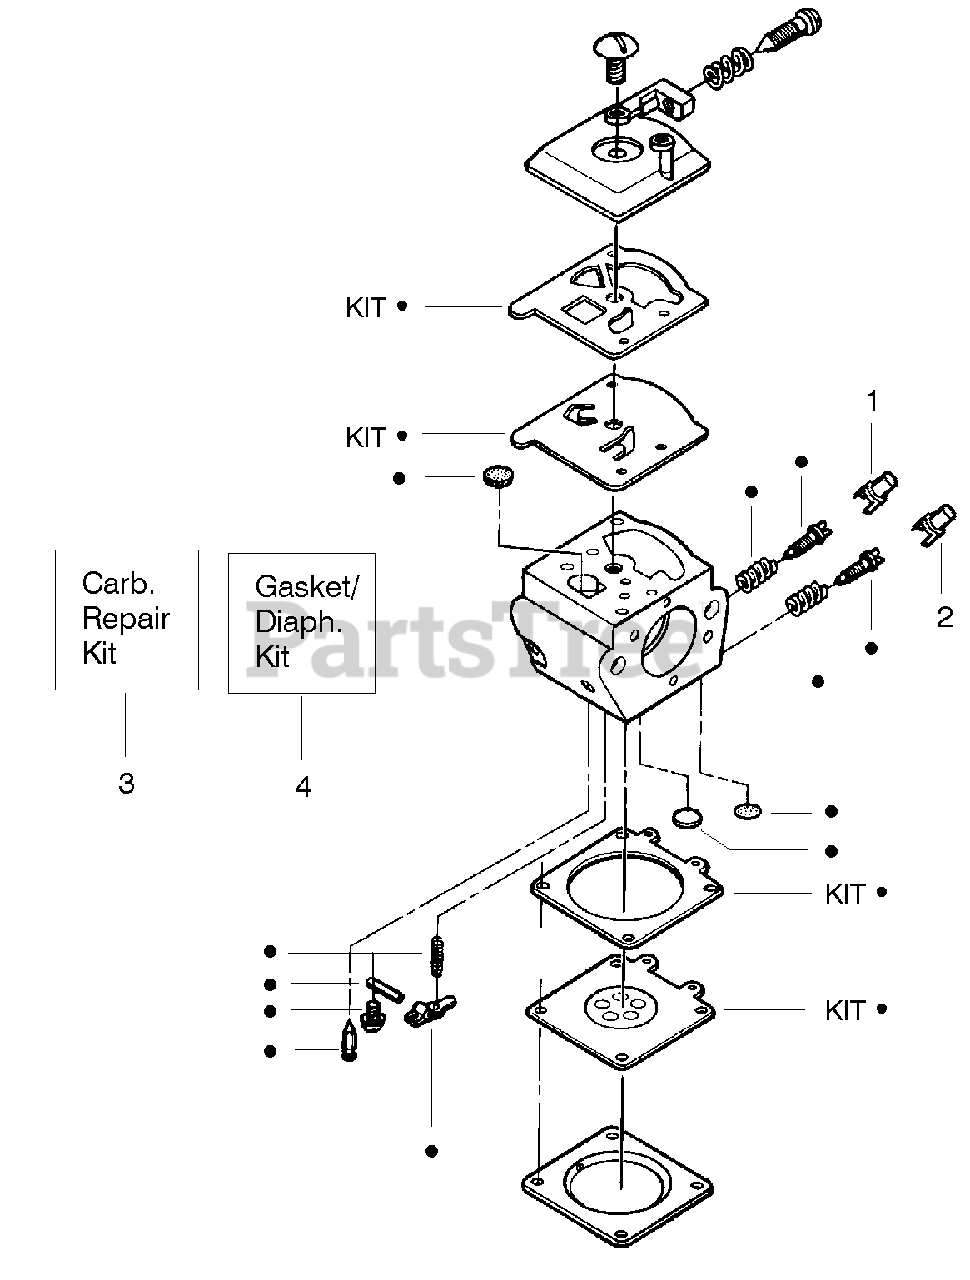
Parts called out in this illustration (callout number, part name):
1	Limiter Cap-High
2	Limiter Cap-Low
3	Carburetor Repair Kit
4	Gasket/Diaphragm Kit
